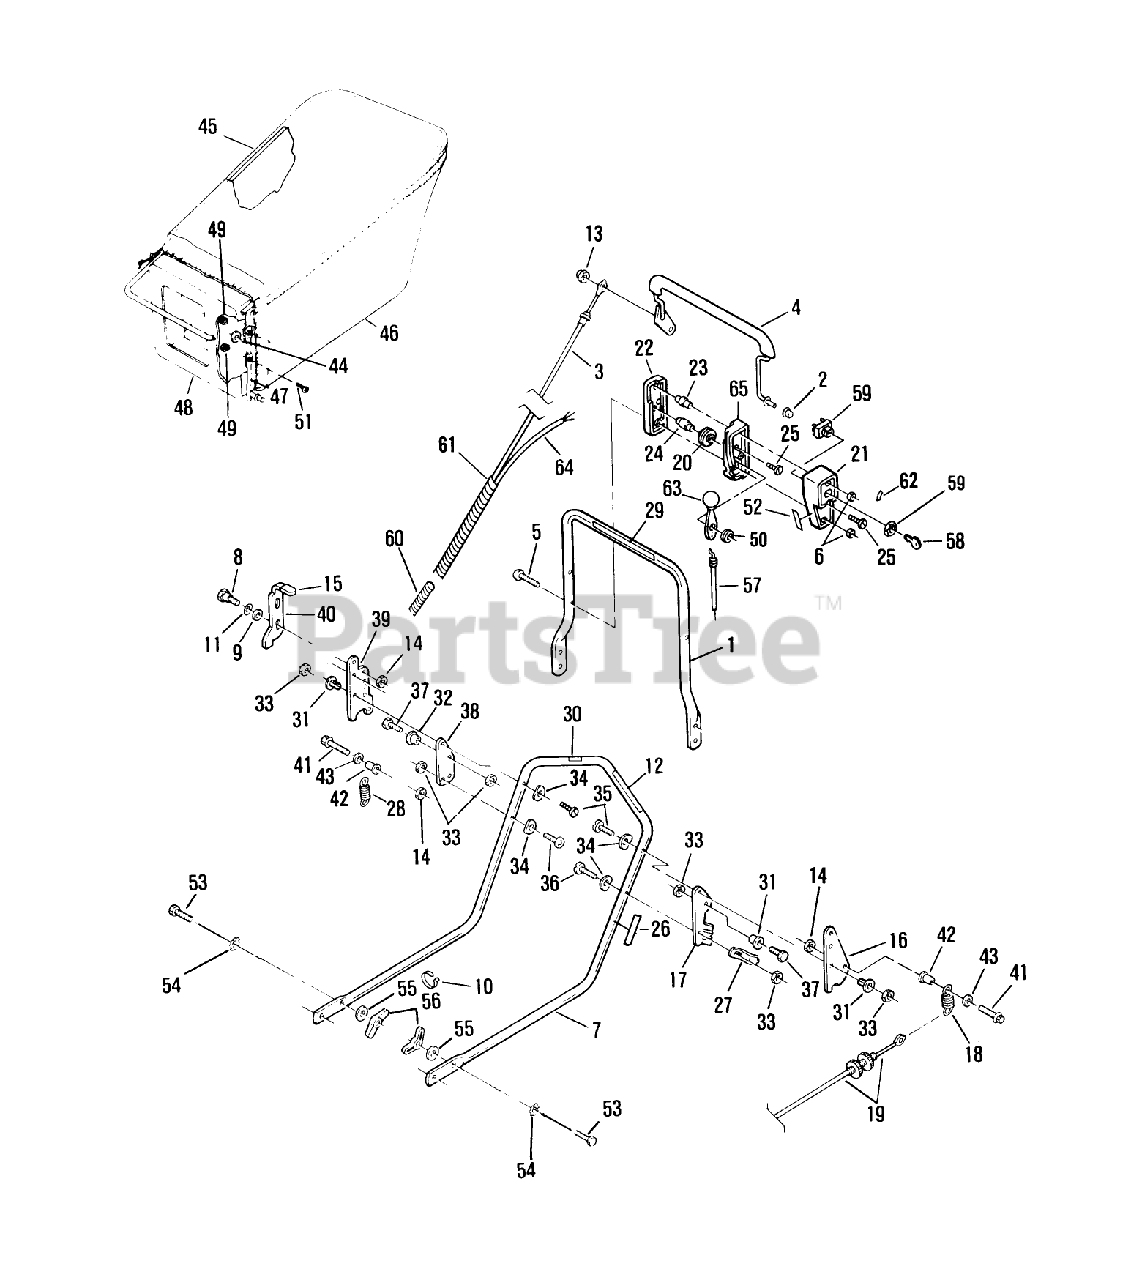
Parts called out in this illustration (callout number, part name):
3	CONTROL CABLE
5	SCREW
6	NUT C/LOCK E
7	HANDLE SECTION
8	BOLT RB&W
9	WASHER M
13	NUT ACORN
14	LOCKNUT E
15	KNOB (S&R)
18	SPRING
19	CABLE AY
20	PULLEY PL
21	CASE THROTTLE
22	OUTER CONTROL CASE
23	COLUMN
24	PIN SKF
25	SCREW
33	NUT-LOCK F
34	WASHER-CURVED
35	SCREW LARSON
42	SPACER ROCKFORD
43	WASHER
44	WASHER
45	HANGER BAG TROX
48	BAG ADAPTOR PL
49	LOCKNUT E
50	WASHER-SPRING
55	WASHER
56	NUT-WING
57	T/CABLE WESCON
63	LEVER&KNOB AY WES
